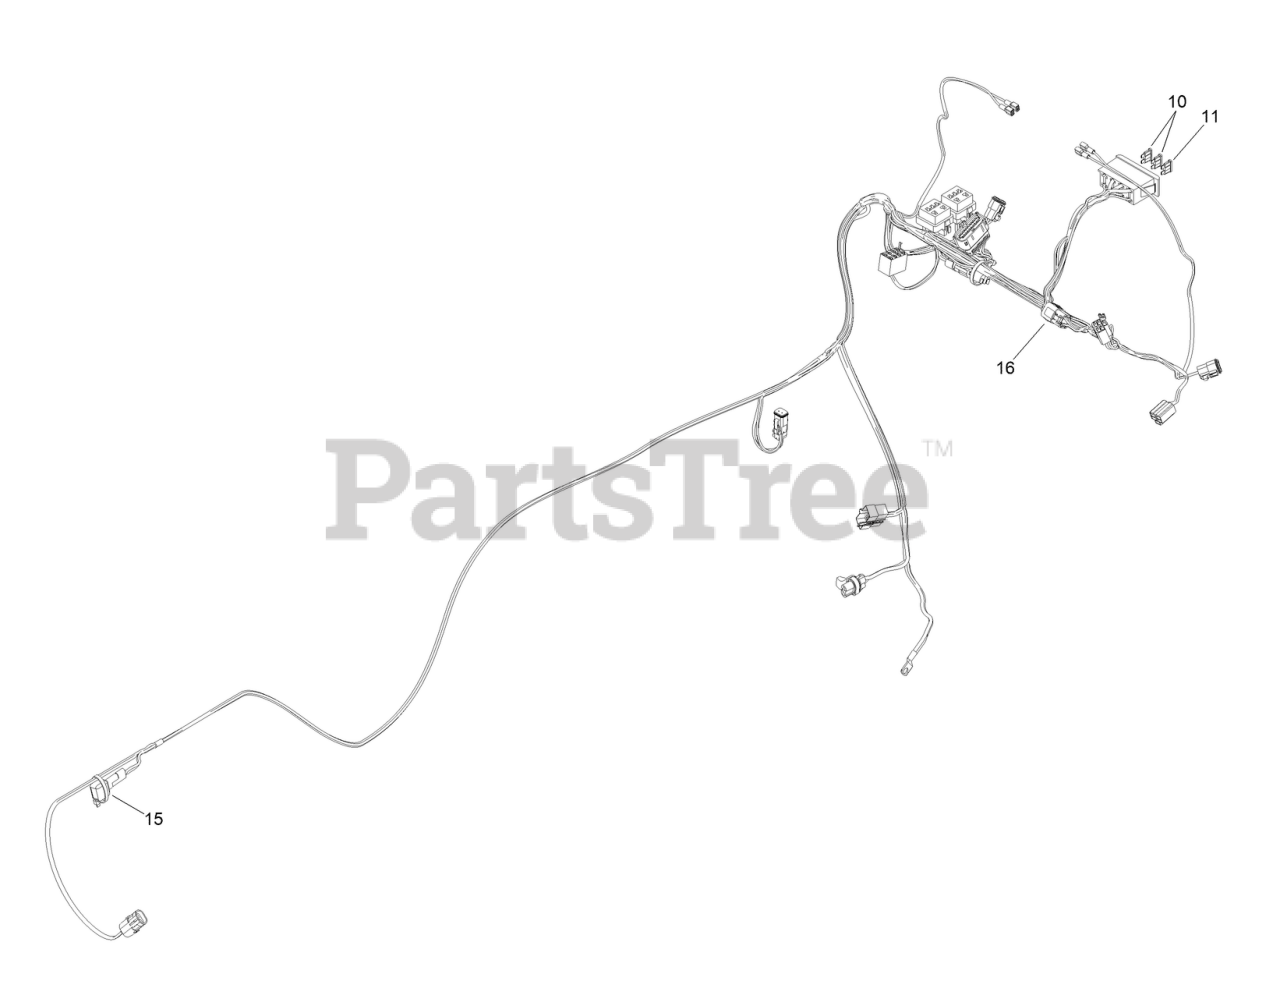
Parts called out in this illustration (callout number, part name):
10	Fuse-Blade, 20 Amp
11	FUSE-BLADE, 10 AMP
16	CAP-PLUG, 6 WAY
